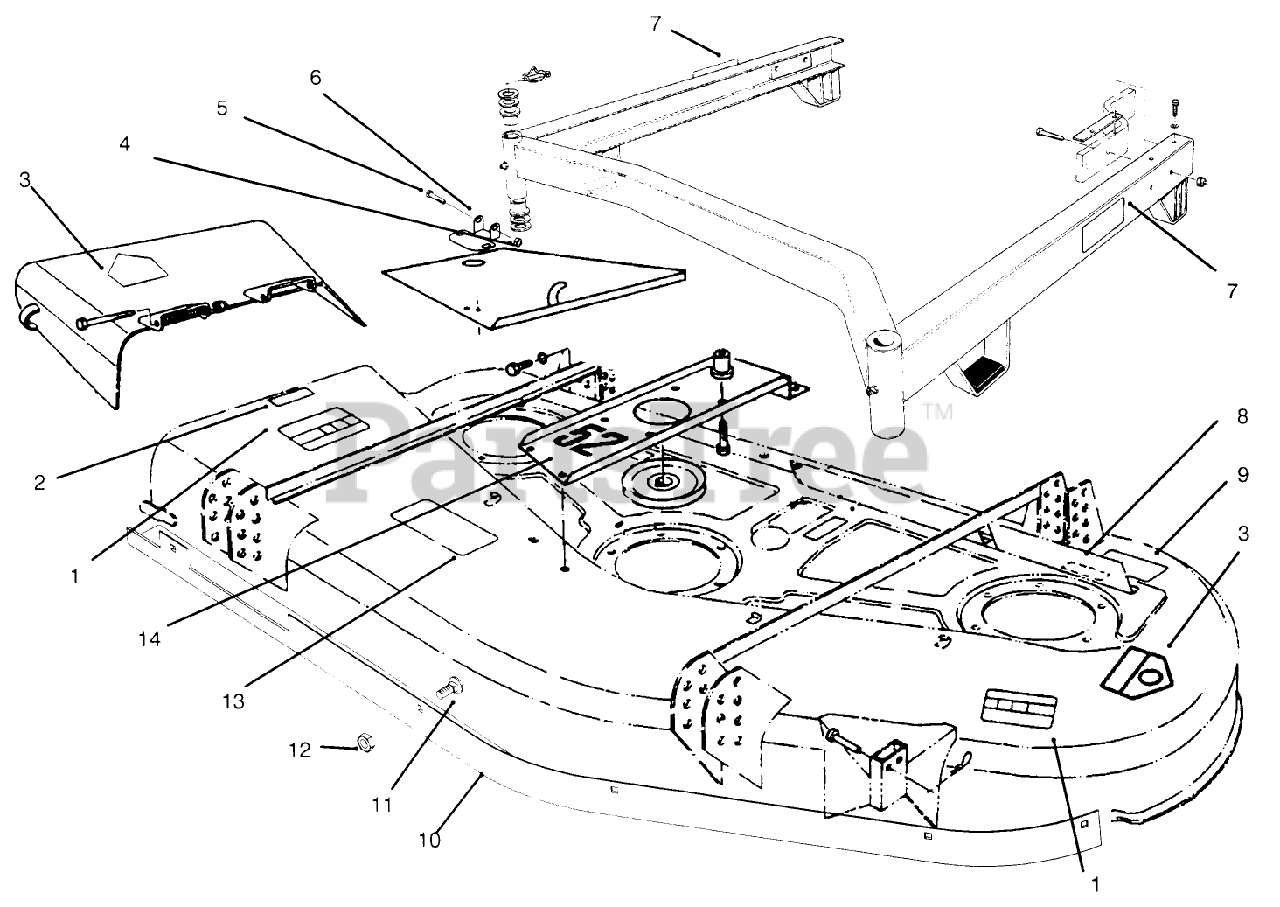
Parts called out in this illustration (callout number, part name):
1	DECAL-DANGER
2	DECAL - WARNING
3	DECAL-DANGER
4	NUT-LOCK, NI
5	SCREW-HH
6	RETAINER-LATCH
7	DECAL-HOC
8	DECAL-DANGER
9	DECAL-TORQUE, BLADE BOLT
10	Baffle
11	SCREW-CARR
12	NUT-LOCK, NI
13	DECAL - WARNING
14	DECAL
